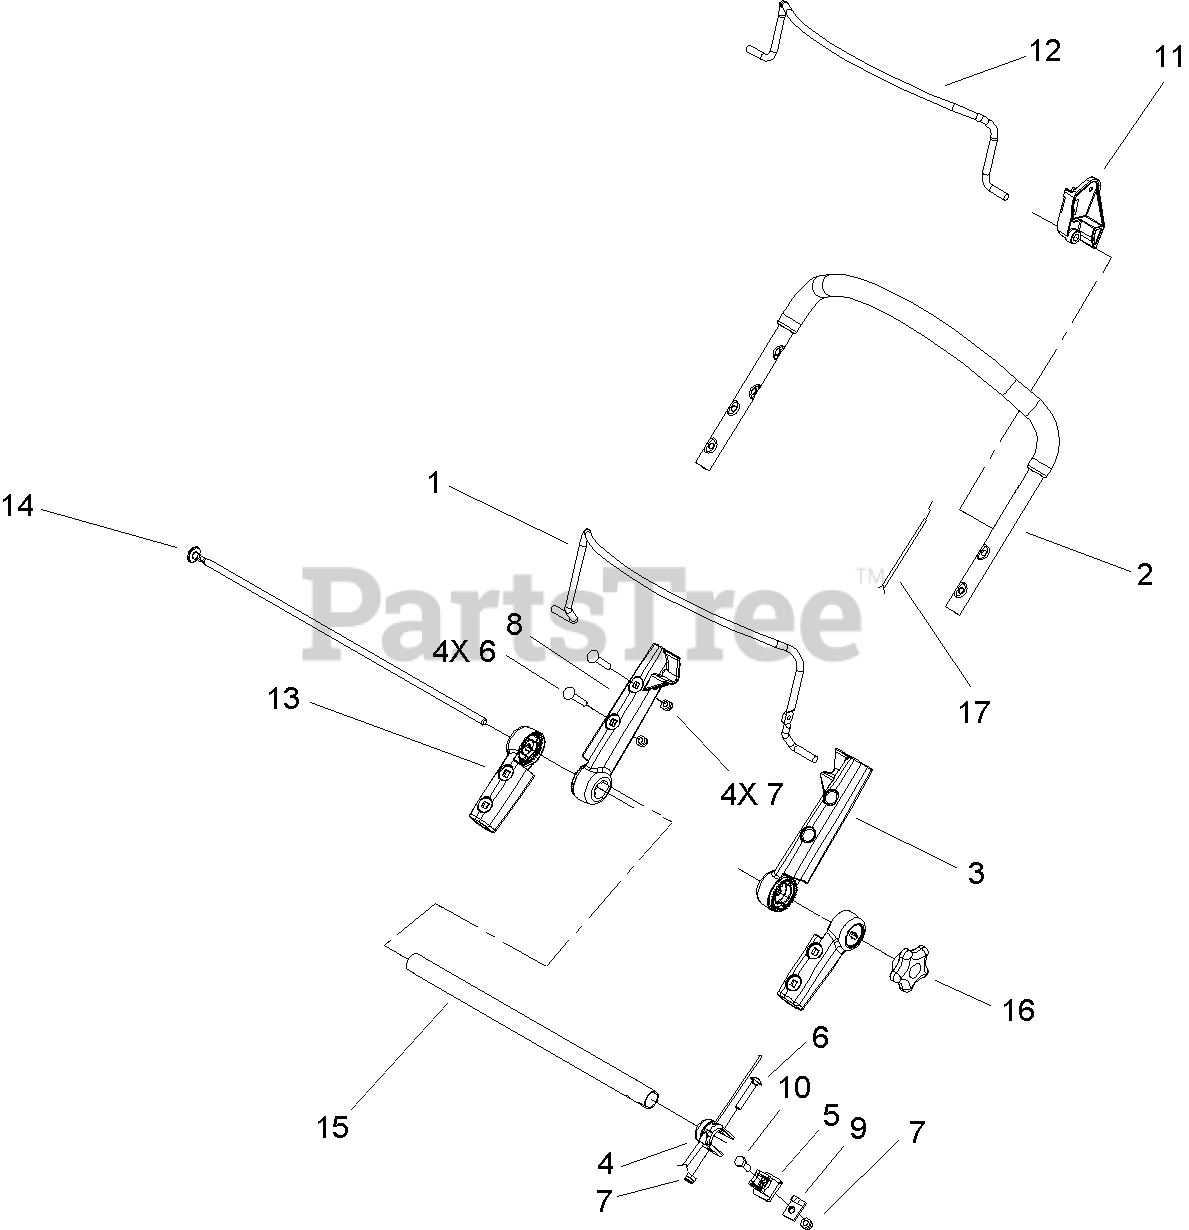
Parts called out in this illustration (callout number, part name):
2	HANDLE ASM
3	MOUNT-HANDLE, LH
4	CABLE-BRAKE
5	SUPPORT-MOUNT, CABLE
6	SCREW-CARR
7	NUT-LOCK, NI
8	MOUNT-HANDLE, RH
9	CLAMP-CABLE
10	SCREW-HH
11	STOP-BAIL
12	BAIL-TRACTION
13	MOUNT-HANDLE, LOWER
14	ROD-THREADED
17	CABLE-TRACTION
